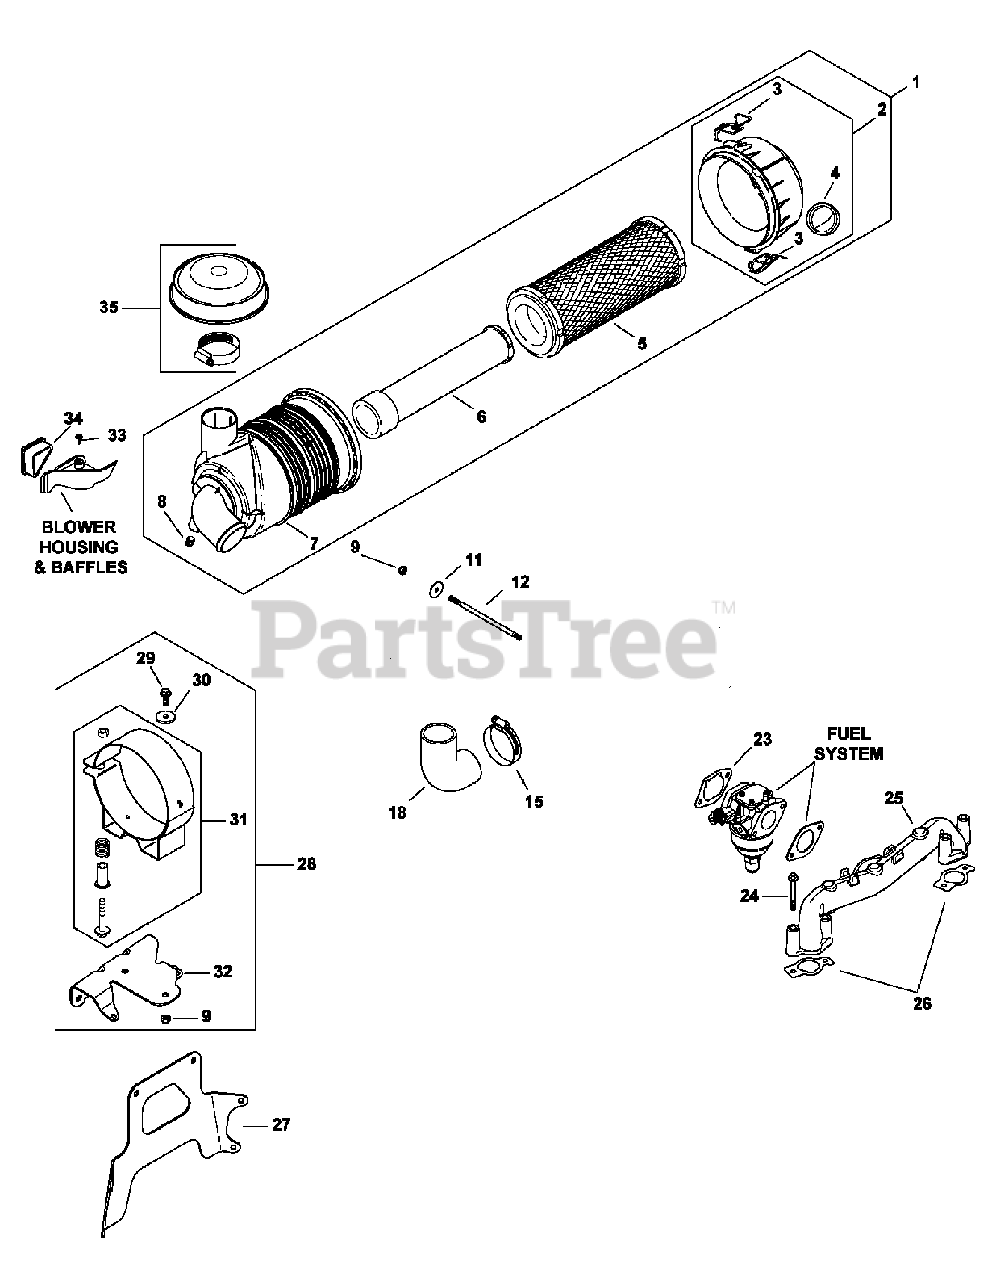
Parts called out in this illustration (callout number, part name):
1	Air Cleaner Assembly
2	Cover Assembly
3	Clip
4	Dust Ejector Valve
5	Primary Air Filter Element
6	Secondary Air Cleaner Element
9	Hex Nut M6X1.0
11	Not used in this application
12	Stud M6X1.0X180
18	Air Cleaner Hose
23	Air Cleaner Base Gasket
24	Hex Flange Screw
25	Intake Manifold
26	Intake Manifold Gasket
27	Main Support Bracket
28	Not used in this application
29	Hex Flange Screw
30	Plain Washer
31	Air Cleaner Bracket
32	Air Cleaner Mounting Bracket
33	Tapping Screw
34	Blower Housing Cover
